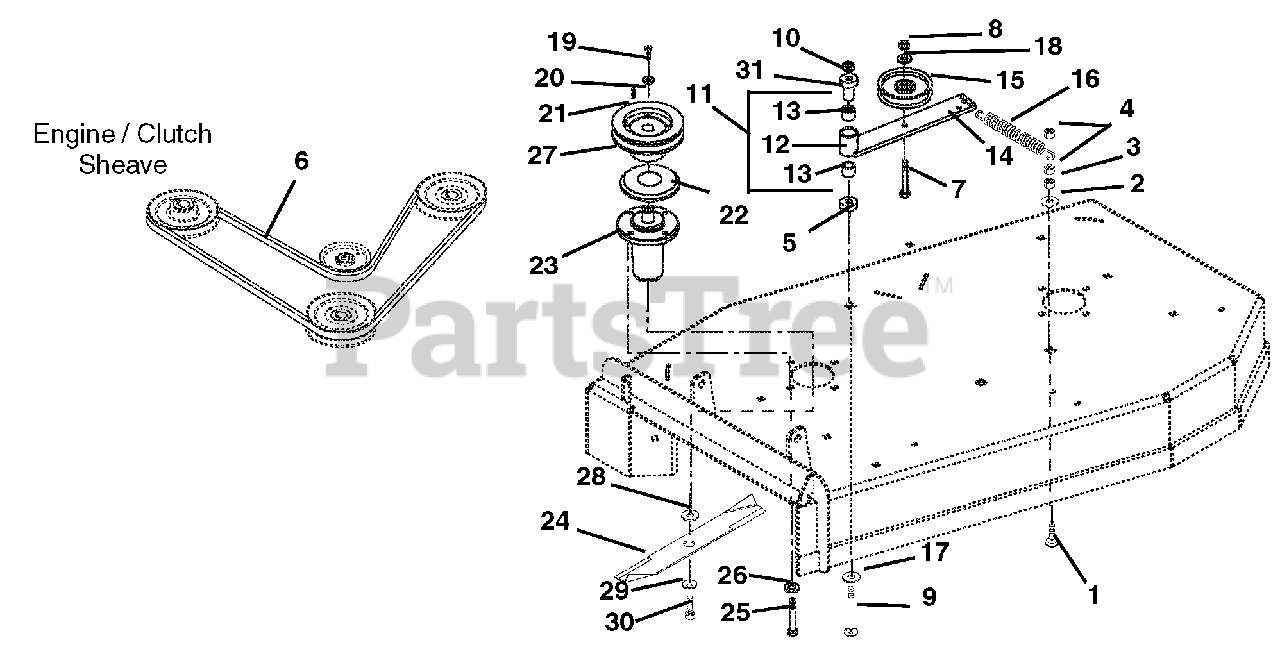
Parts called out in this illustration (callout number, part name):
1	Bolt-Round Head Square Neck .38-16 x 1.50 Grade 5
2	Washer-Locking .38 x .094 Regular
3	Nut-Hex .38-16
4	Nut-Locking-Center .38-16
5	Washer-Flat-Steel .515 x 1.625 x .25
6	V-Belt B-Section 36.70 x .650 (105, 312)
7	Bolt-Round Head Square Neck .38-16 x 2.75 Grade 5
8	Nut-Locking-Center .38-16
9	Bolt-Round Head Square Neck .50-13 x 3.75 Grade 5
10	Nut-Locking-Center .50-13
11	Assembly, Idler Pivot Arm (Contains Items 12 & 13)
12	Weldment, Idler Pivot Arm
13	Bearing, 1.00 x 1.12 x .75
14	Bearing, Pedestal Powdered Metal
15	Idler-Flat 4.00 x .38 (2.00 W)
16	Spring, Extension
17	Washer-Flat-Steel .755 x 1.375 x .062
18	Washer-Flat-Steel .375 x 1.125 x .065
19	Bolt-Hex .38-16 x 1.00 Grade 8
20	Washer-Cupped-Serrated .375
21	Key-Straight .25 x 1.00 x .25
22	Slinger-Dust
23	Assembly, Maintenance Free Spindle
24	Blade- Mower (105)
25	Bolt-Hex .38-16 x 1.00 Grade 5
26	Washer-Locking .38 x .094 Regular
27	Pulley
28	Washer, Flat .64 x 1.81 x .250
29	Washer-Bellville .63 x 1.625 x .14
30	Bolt-Hex .62-18 x 1.75 Grade 8
31	Bearing, Pedestal Powdered Metal
